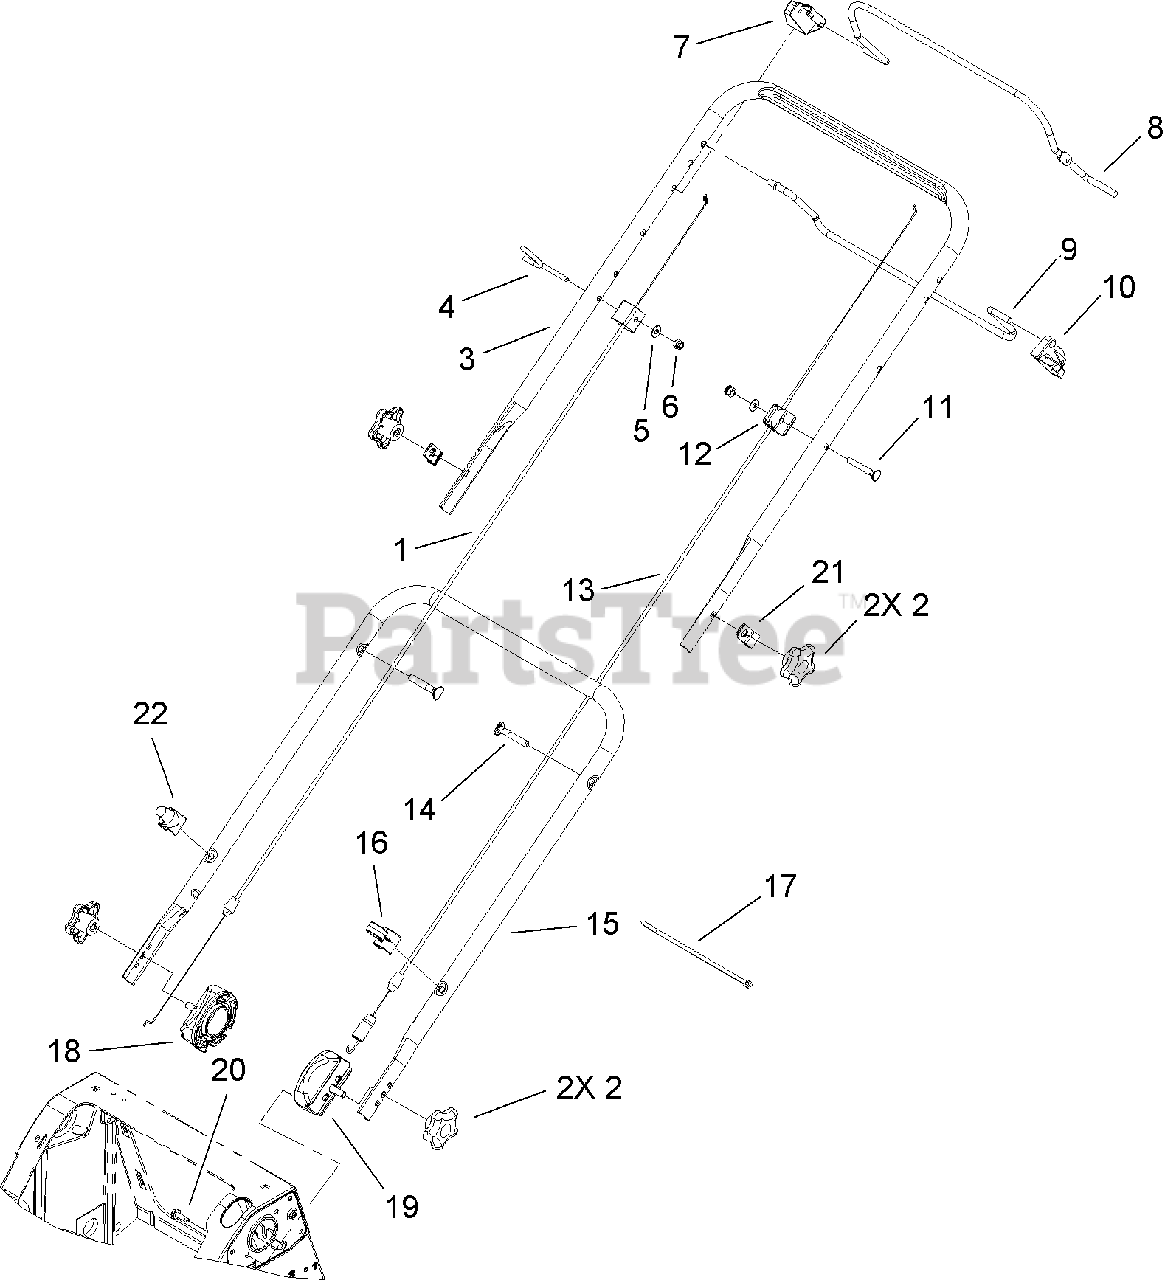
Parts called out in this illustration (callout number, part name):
1	Cable-Brake
2	KNOB-HANDLE
3	Handle-Upper
4	GUIDE-ROPE
5	WASHER-FLAT
6	NUT-LOCK, NI
7	STOP-PIVOT
9	Bail-Control
10	Stop-Pivot
12	ANCHOR-CABLE, UPPER
13	CABLE-TRACTION
14	SCREW-HANDLE
15	HANDLE-LOWER
16	Guide-Cable
17	STRAP-TIE
18	RH HANDLE MOUNT ASM
19	LH HANDLE MOUNT ASM
20	SCREW-HWHTF
22	GUIDE-ROPE, LOWER
